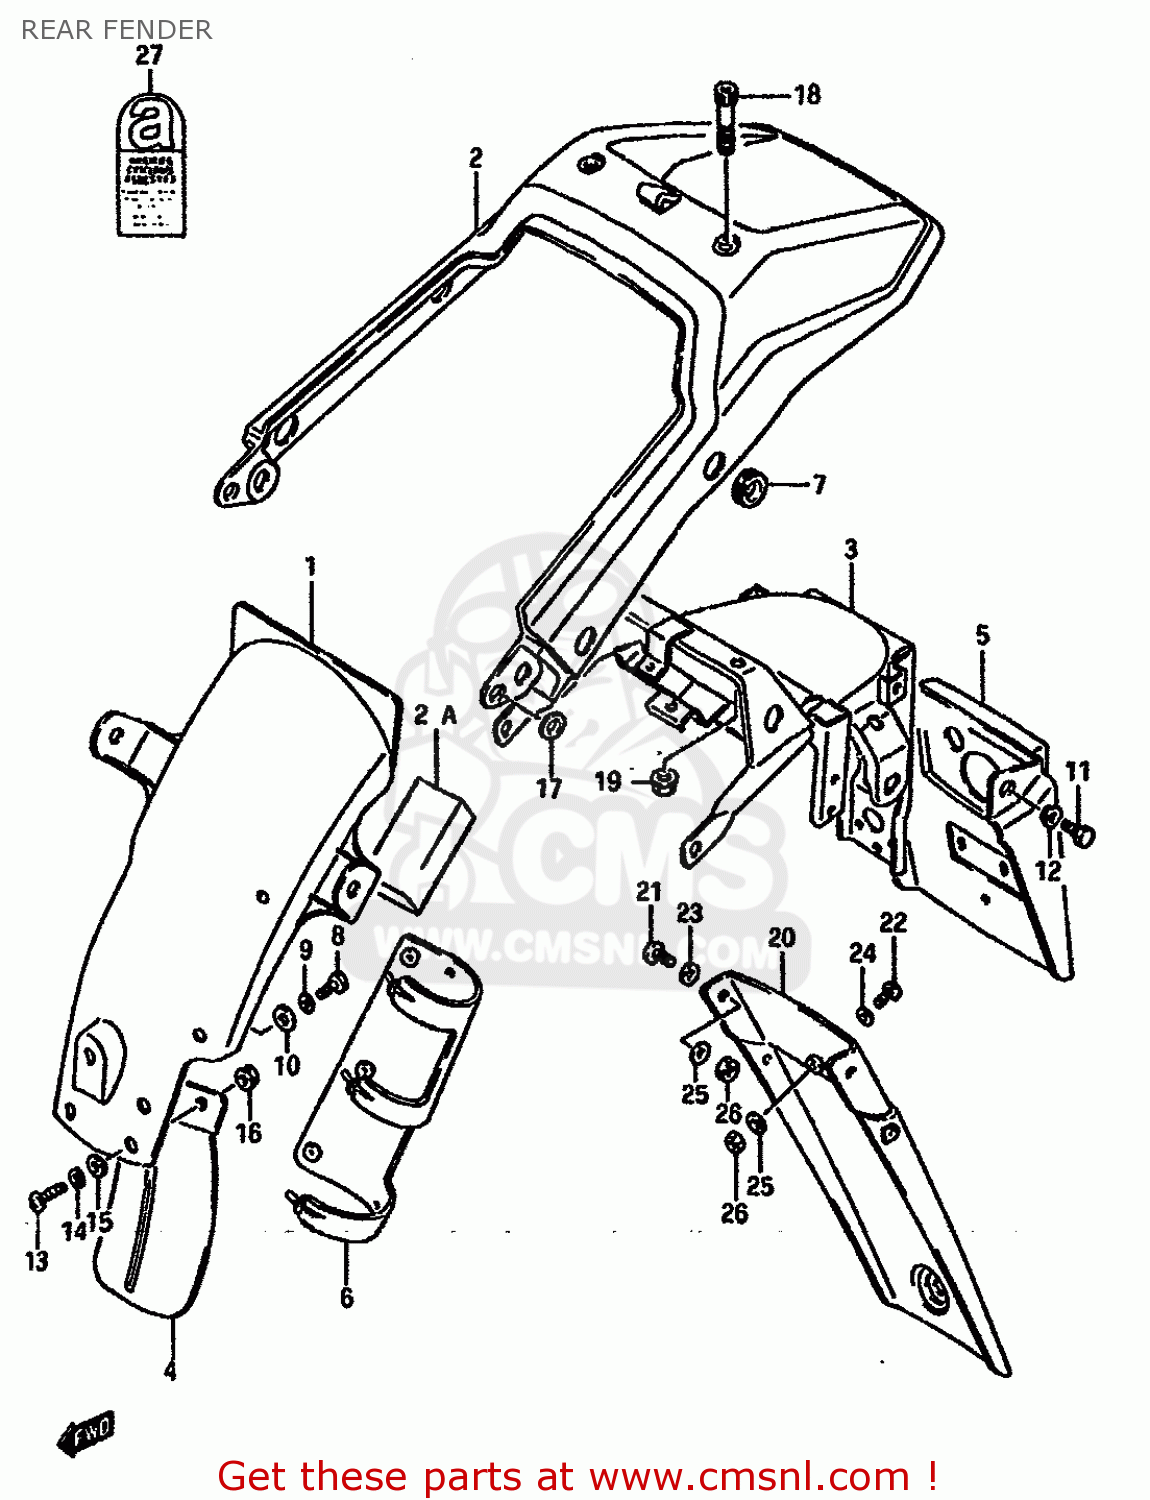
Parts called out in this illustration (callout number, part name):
1	BODY,REAR FENDER FRONT
2	BODY,REAR FENDER REAR (RED)
2A	DUST SEAL,REAR FENDER
3	REINFORCEMENT
4	GUARD,REAR FEN
5	EXTENSION,REAR FENDER
6	GUARD,MUD
7	GROMMET
8	BOLT 6X16
9	WASHER,LOCK
10	WASHER
11	BOLT
12	WASHER
13	SCREW
14	WASHER
15	WASHER
16	NUT
17	WASHER
18	BOLT
19	NUT
20	MUD GUARD,REAR FENDER
21	SCREW 6X12
22	SCREW(6X25)
23	WASHER
24	WASHER,LOCK
25	WASHER(6.5X16X1.2)
26	NUT
27	LABEL,ASBESTOS WARNING
